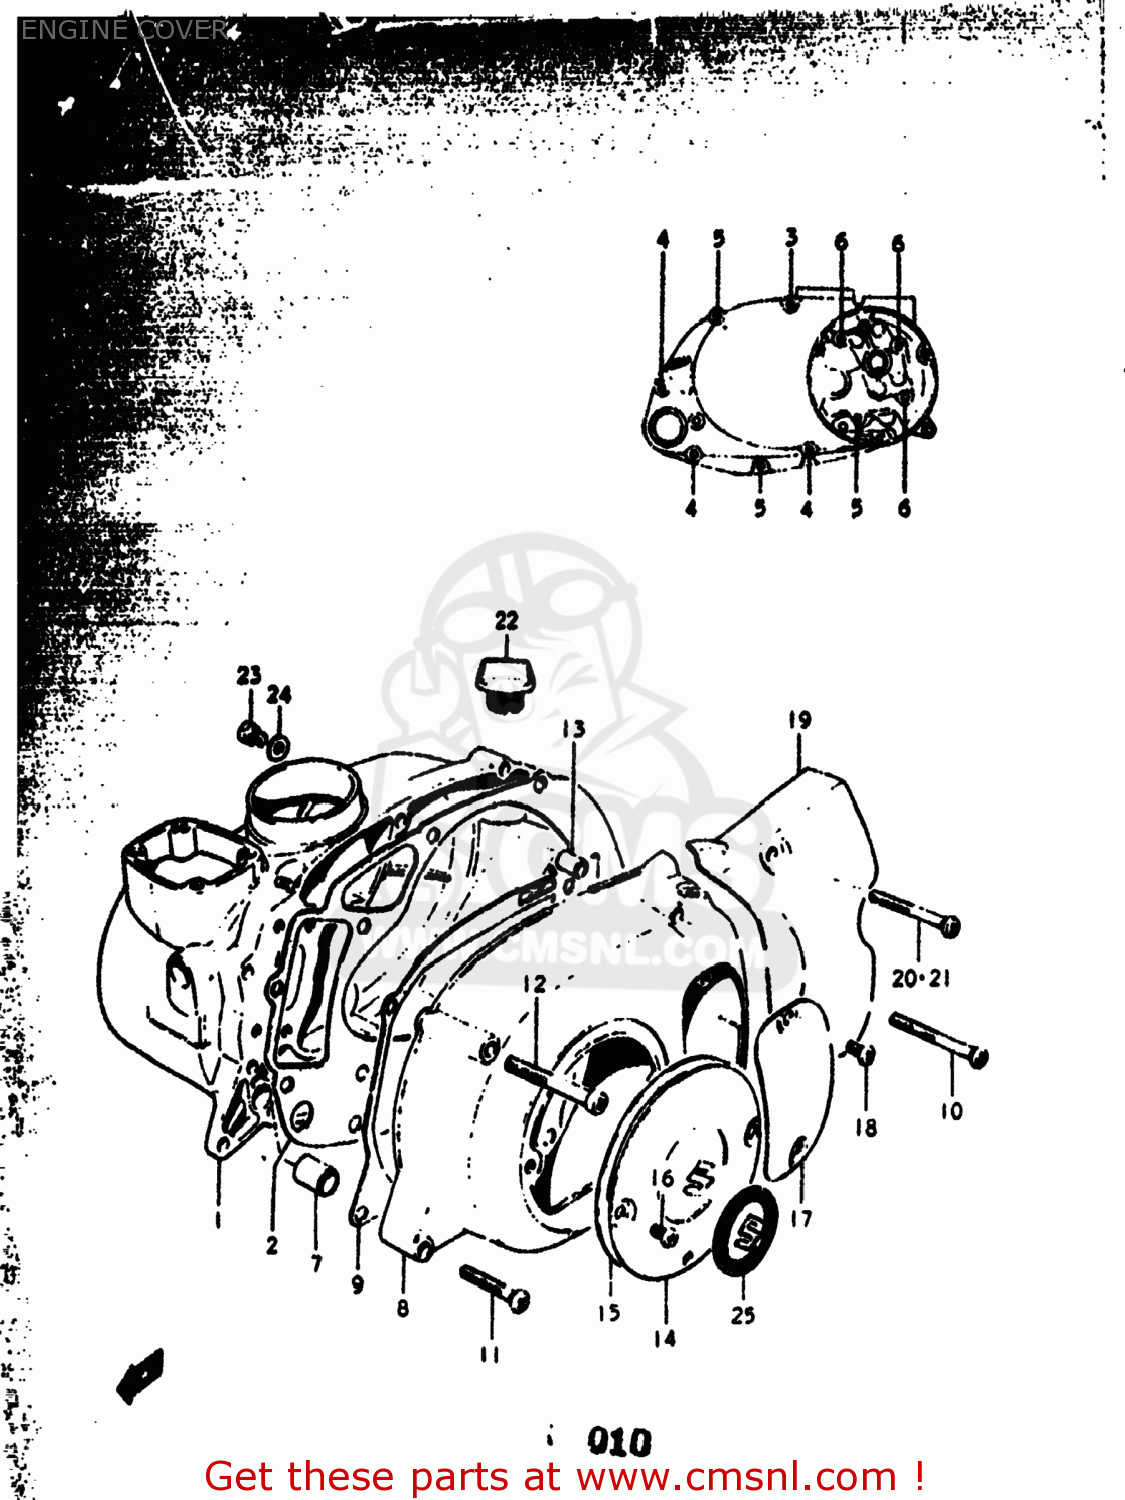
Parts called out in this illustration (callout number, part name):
1	COVER,CLUTCH
2	GASKET,CLUTCH COVER (MCA)
3	SCREW 6X70
4	SCREW 6X60
5	SCREW
6	SCREW
7	PIN
8	COVER
9	GASKET,MAGNETO COVER (NAS)
10	SCREW
11	SCREW
12	SCREW
13	PIN
14	CAP,MAGNETO INSPECTION
15	GASKET,MAGNETO INSPECTION (NAS)
16	SCREW
17	CAP,CLUTCH RELEASE ADJUST
18	SCREW
19	COVER,SPROCKET
20	SCREW
21	SCREW (6X35)
22	PLUG
23	SCREW(6X10)
24	GASKET(6.2X11X1) (NAS)
25	EMBLEM,MAGNETO
